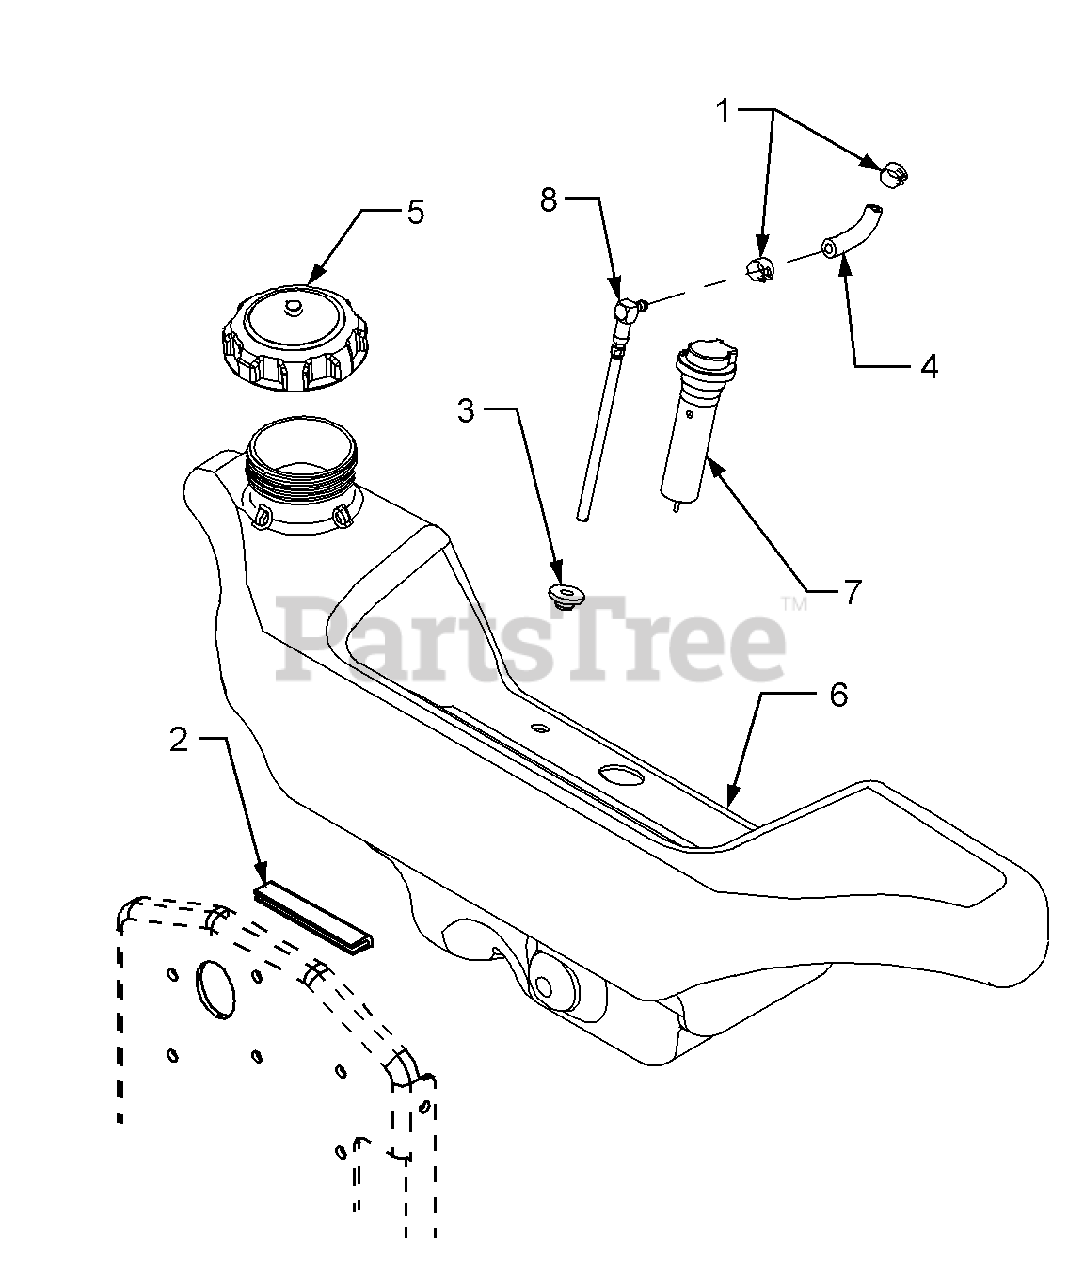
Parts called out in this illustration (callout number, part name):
1	Clamp, Hose
2	Trim, Tank Protector
3	Bushing, Rubber
4	Fuel Line
5	Cap, Fuel
6	Tank, Fuel, 4.5 Gallon
7	Sensor, Low Fuel
8	Fitting, Fuel Pickup
